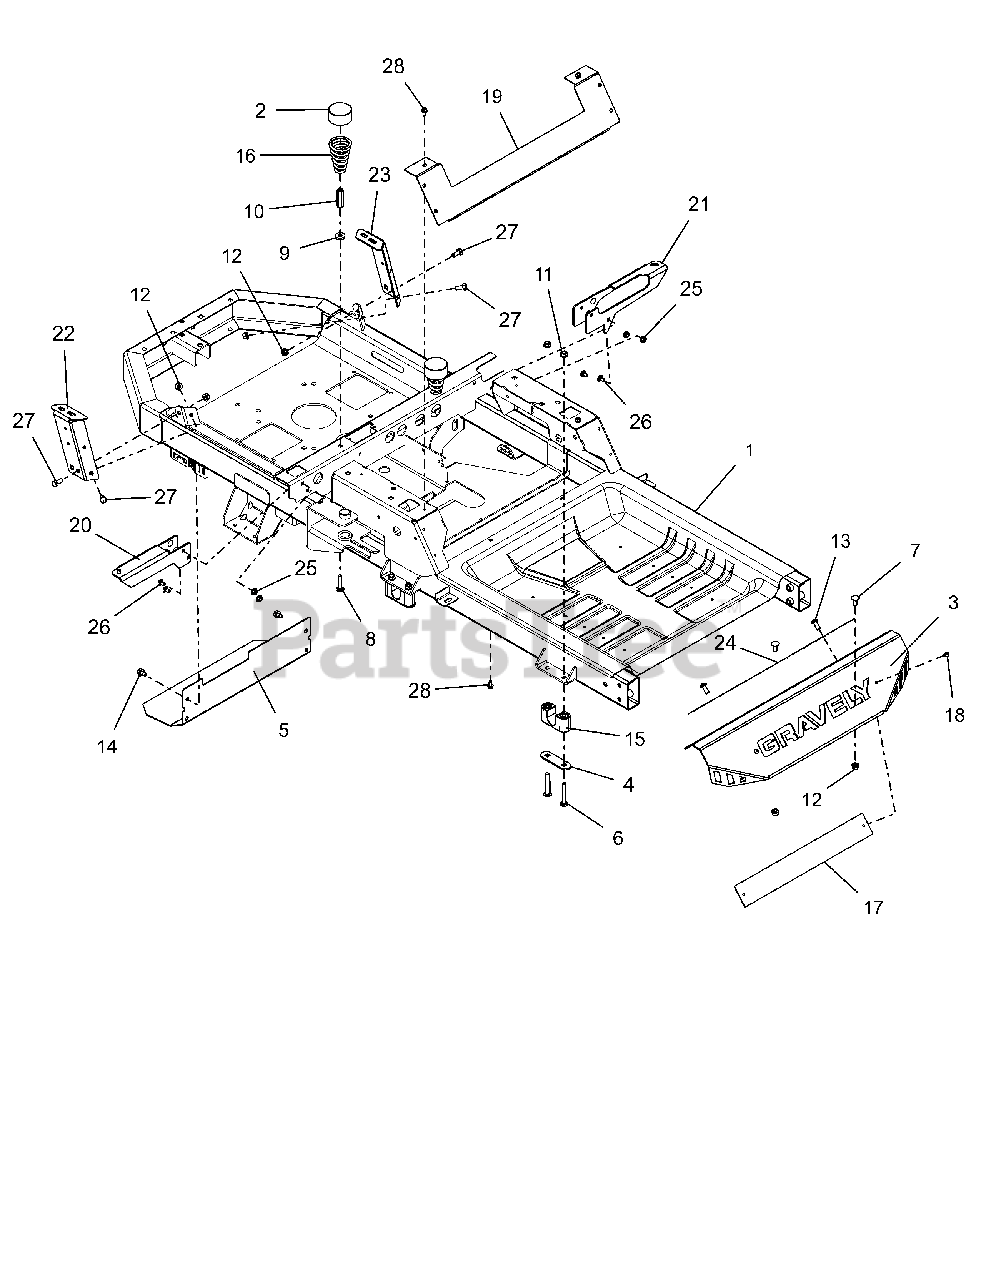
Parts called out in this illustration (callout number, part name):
1	KIT, ZT-X/XL FRAME SERVICE
3	KIT, FOOTPLATE W/DECAL-ZTX
4	PLATE, BEARING SUPPORT
5	HEAT, SHIELD
6	BLT-RDHDSQSHNK .31-18X2.25 YWZ
7	BLT,RHSN .31-18X.75 G5 ZCC
8	BLT,RHSN .31-18X1.50 G5 ZCC
9	WSHR, FLT .328X.870X.179 ZCC
10	NUT, COUPLING 5/16-18 X 1 3/4
11	NUT,LK-CTR-FLG .31-18 GF ZCC
12	NUT-LK-TOP-FLG .312-18 GF ZCC
13	SCR-RDHDSKTAP .31-18 X .75
14	SCR,TAP .312-18X.50 HWH TR ZCC
15	BSHG, DECK LIFT PIVOT
16	SPRING, SEAT
17	PLATE, BACK FOOT-REST XL
18	RIVET, .1875 AL/AL .126-.250
19	PLATE, SEAT KICK
20	BRKT,CROSS EXTENSION - LH
21	BRKT,CROSS EXTENSTION - RH
22	MOUNT,FENDER-RH EXTENSION
23	MOUNT,FENDER-LH EXTENSION
24	GRIP, FOOT PLATE
25	NUT-LK-CTR-FLG .25-20 ZC120
26	BLT, RHSSN.25-20X.500 G5 ZCC
27	BLT,HEX .31-18X.75 G5 ZCC
28	SCR-TAP .25-20X.50 HWH ZCC
